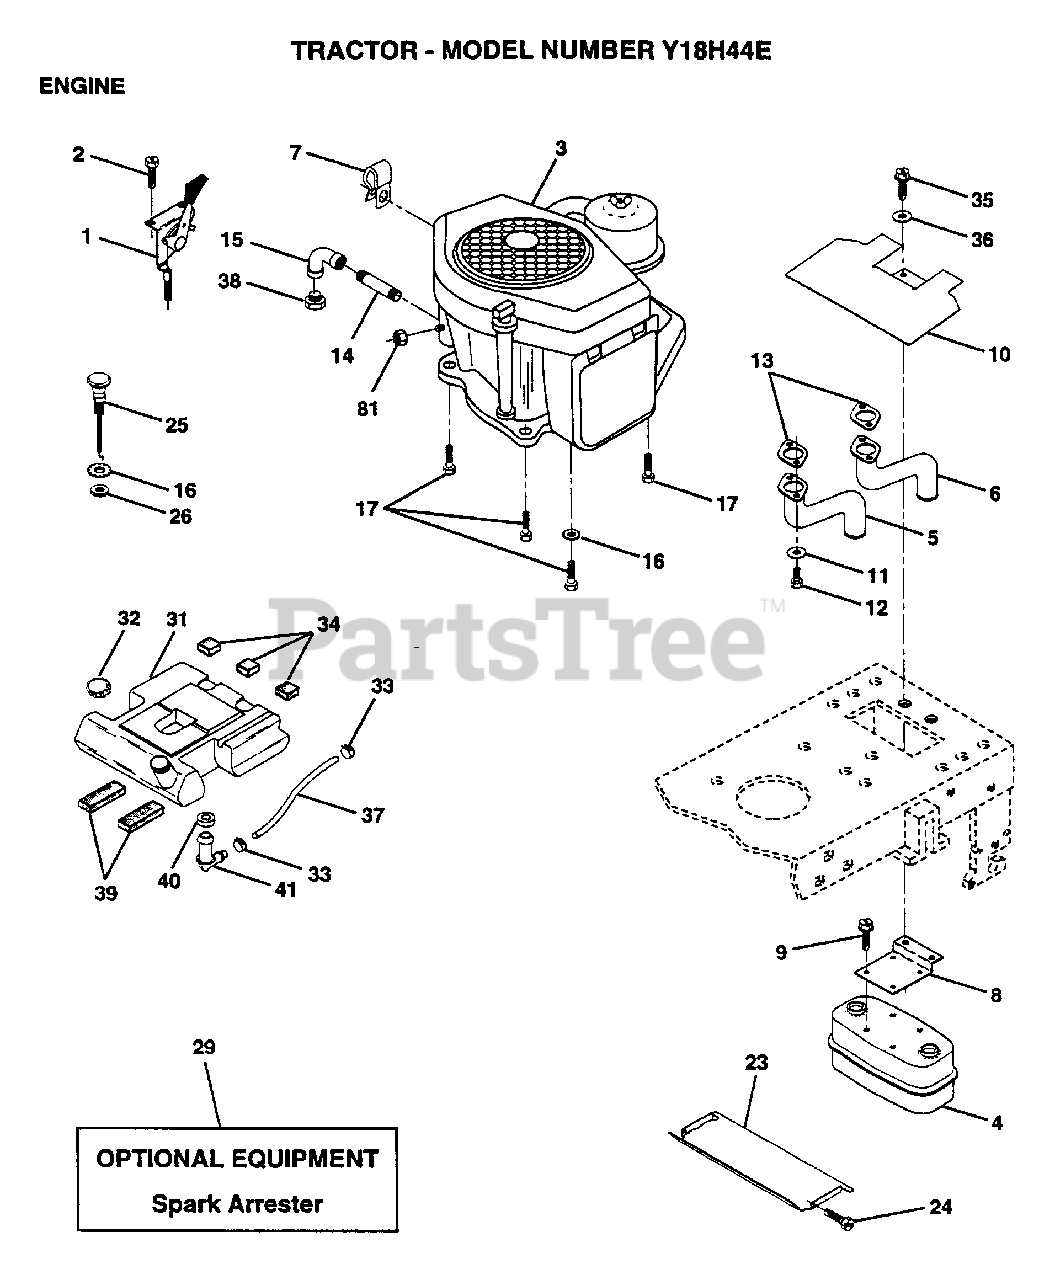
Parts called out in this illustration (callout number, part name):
1	CONTROL.THROTTL
2	SCREW LT
5	"TUBE,MANIFOLD LH"
6	"TUBE,MANIFOLD RH"
7	CLIP T
8	BRACKET MUFFLER
9	SCREW ST
10	SHIELD.HEAT.
11	LOCKWASHER
12	SCREW
14	PIPE NIPPLE LT
15	ELBOW
16	LOCKWASHER
17	SCREW LT
23	HEAT SHIELD
24	SCREW
32	CAP ASM FUEL
33	HOSE CLAMP
34	PAD-SPACER LT
35	SCREW
36	WASHER
37	FUEL LINE T
39	PAD IDLER TI
40	BUSHING OUTLET T
41	STEM.TANK.FUEL
81	NUT
